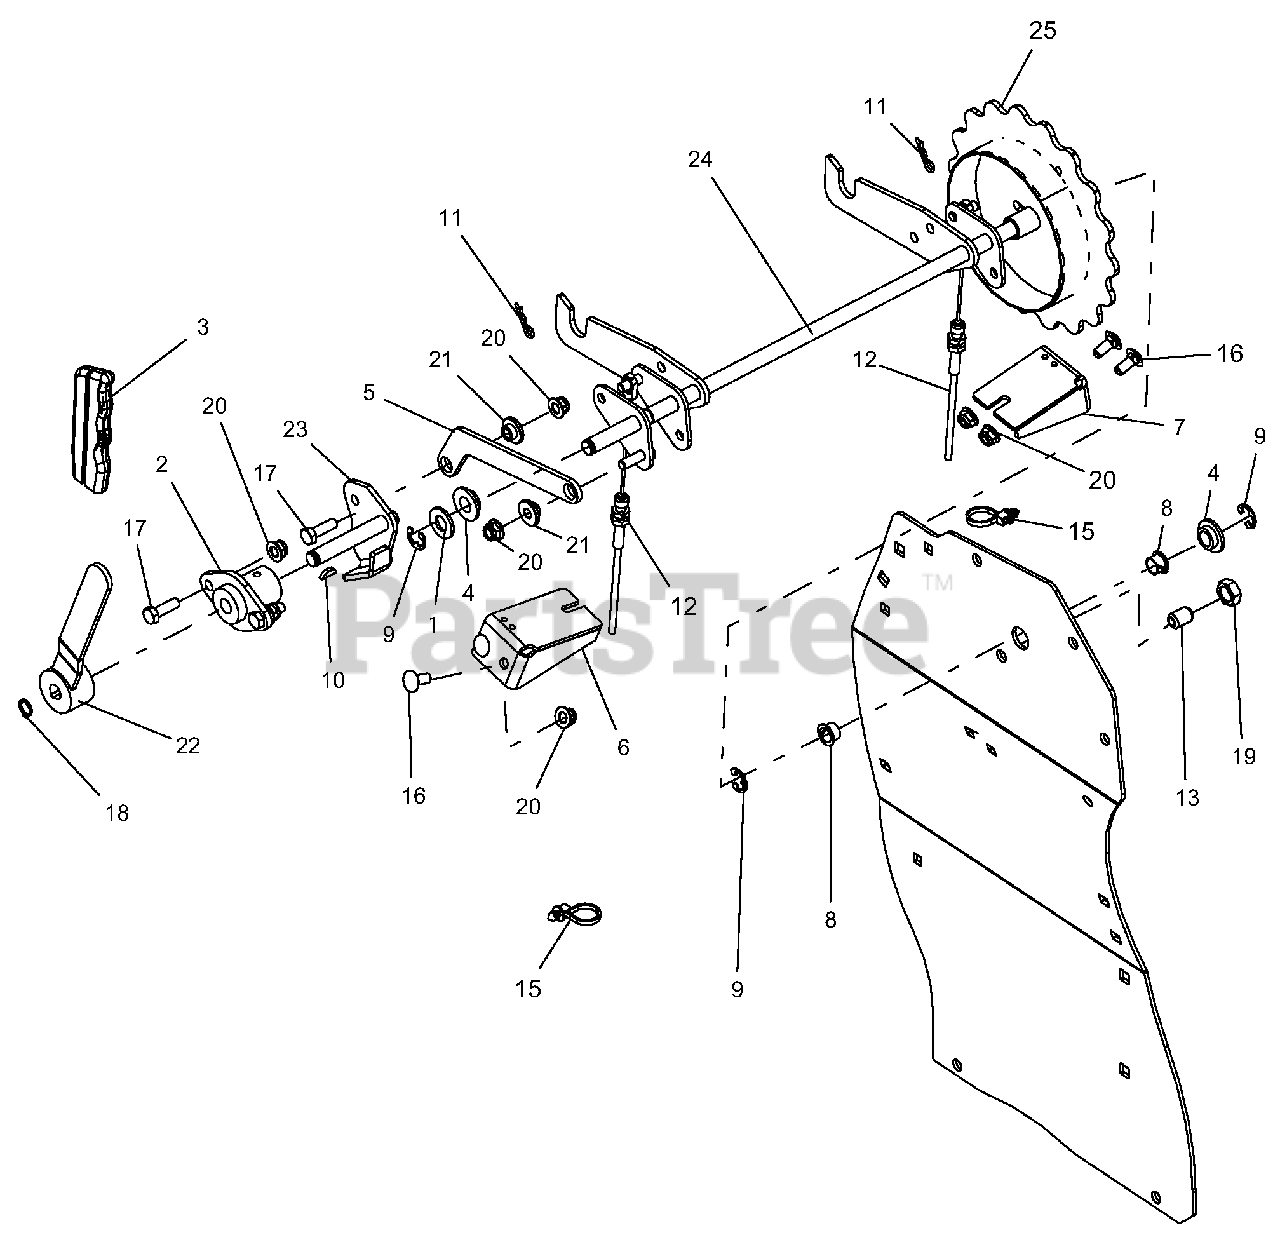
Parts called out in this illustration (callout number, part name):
1	WSHR-FL-STL.531X1.06X.095YWZC
2	BSHG, FLANGE .500 ID
3	GRIP, PARKING BRAKE (YELLOW)
4	BSHG, FLANGE .515X.750X.31X1.12
5	LINK, INTERLOCK
6	BRKT, CABLE MTG.
7	BRKT, LH CABLE MTG
8	BUSHING, POLYLINER - .50 SPLIT
9	RG-RTNG-EXT .500X.042 (E)
10	KEY, WDRF .13x.63 HRD#5 GM124545 P
11	PIN, HAIR INT .08X.18X1.18 YWZC
12	CABLE, PROSTANCE P. BRAKE
13	BALL SPRING PLUNGER, .500-13
15	CABLE TIE W/ TREE (.25 HOLE)
16	BLT-RDHDSQNK .31-18X.75 G5 YWZC
17	BLT-HEX .31-18X1.00 GR5 YWZC
18	RG-RTNG-EXT .500x.050
19	NUT, JAM .500-13 YWZC
20	NUT-LK-NYL-FLG .31-18 YWZC
21	BSHG, FLG .32X.500.344X.880
22	WLDMT, PARKING BRAKE LEVER
23	WLDMT, PARKING BRAKE ACTUATING
24	WLDMT, BRAKE INTERLOCK
25	WLDMT, HEIGHT OF CUT
